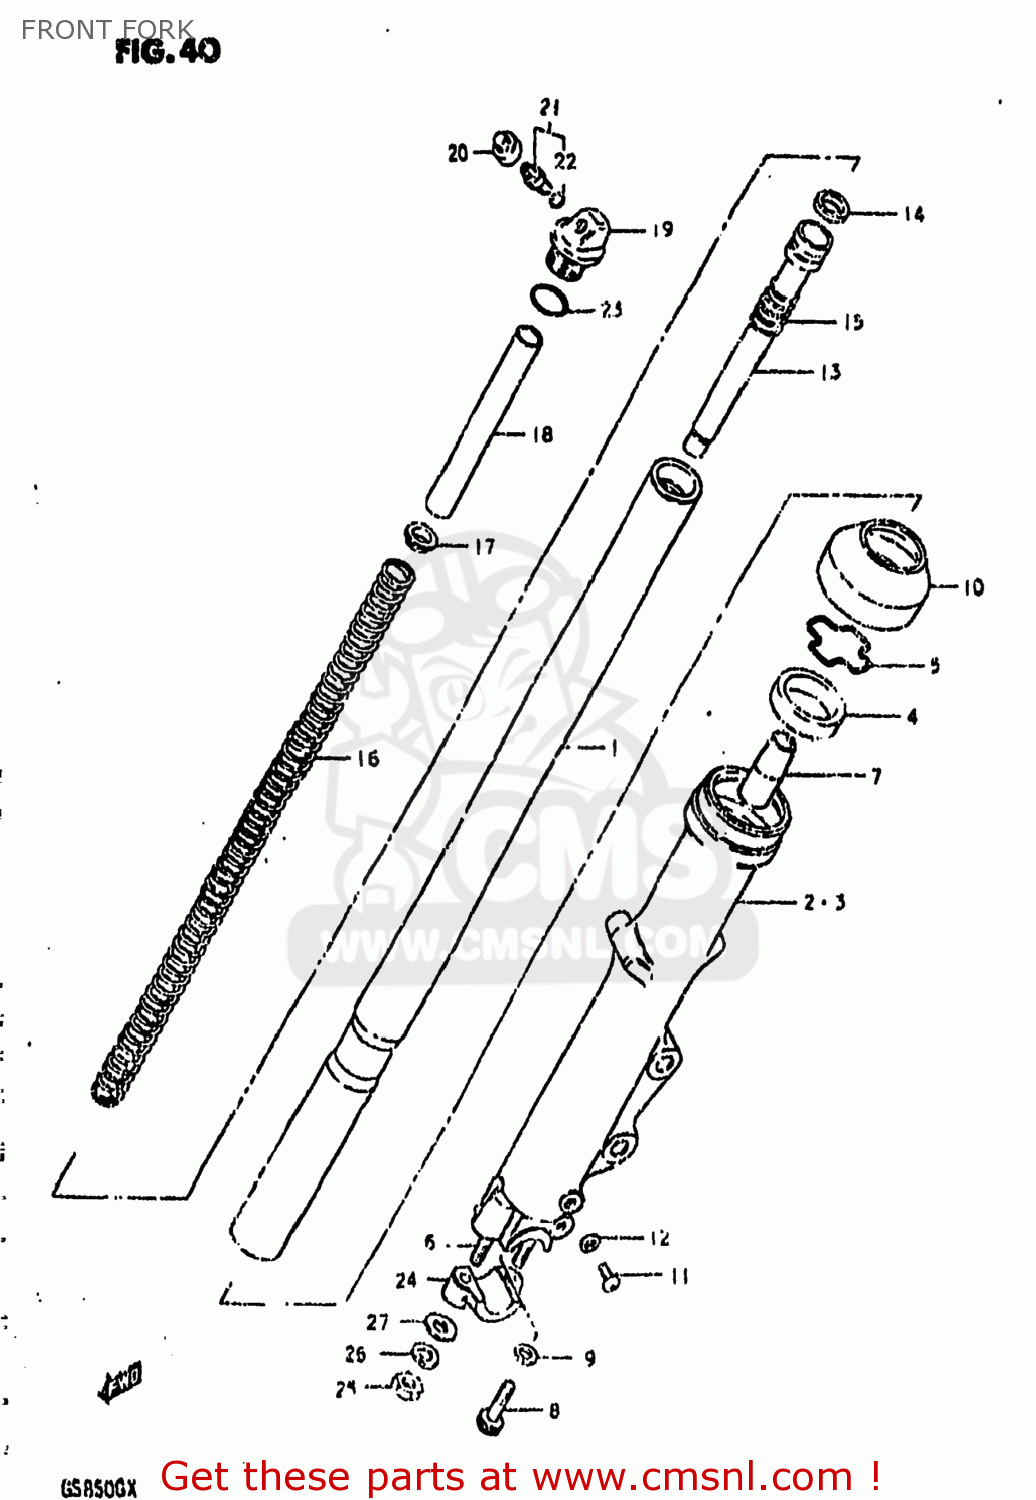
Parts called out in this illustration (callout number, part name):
0	DAMPER ASSEMBLY,LEFT
1	TUBE,FORK,INNER
2	TUBE,FORK,OUTER,RIGHT
3	TUBE,FORK,LEFT,OUTER
4	OIL SEAL,FRONT FORK
5	RING,STOPPER
6	STUD BOLT
7	PIECE,OIL LOCK
8	BOLT,FORK CYLINDER(10X25)
9	GASKET (NAS)
10	SEAL,DUST
11	SCREW
12	GASKET,DRAIN,PLUG (NAS)
13	CYLINDER,FRONT FORK
14	RING,PISTON
15	SPRING,REBOUND
16	SPRING,FRONT FORK
17	GUIDE,FRONT FORK SPRING C
18	SPACER,SPRING
19	CAP
20	CAP,VALVE
21	VALVE
22	O RING
23	O RING
24	HOLDER,AXLE
25	NUT (8MM)
26	LOCK WASHER
27	WASHER
